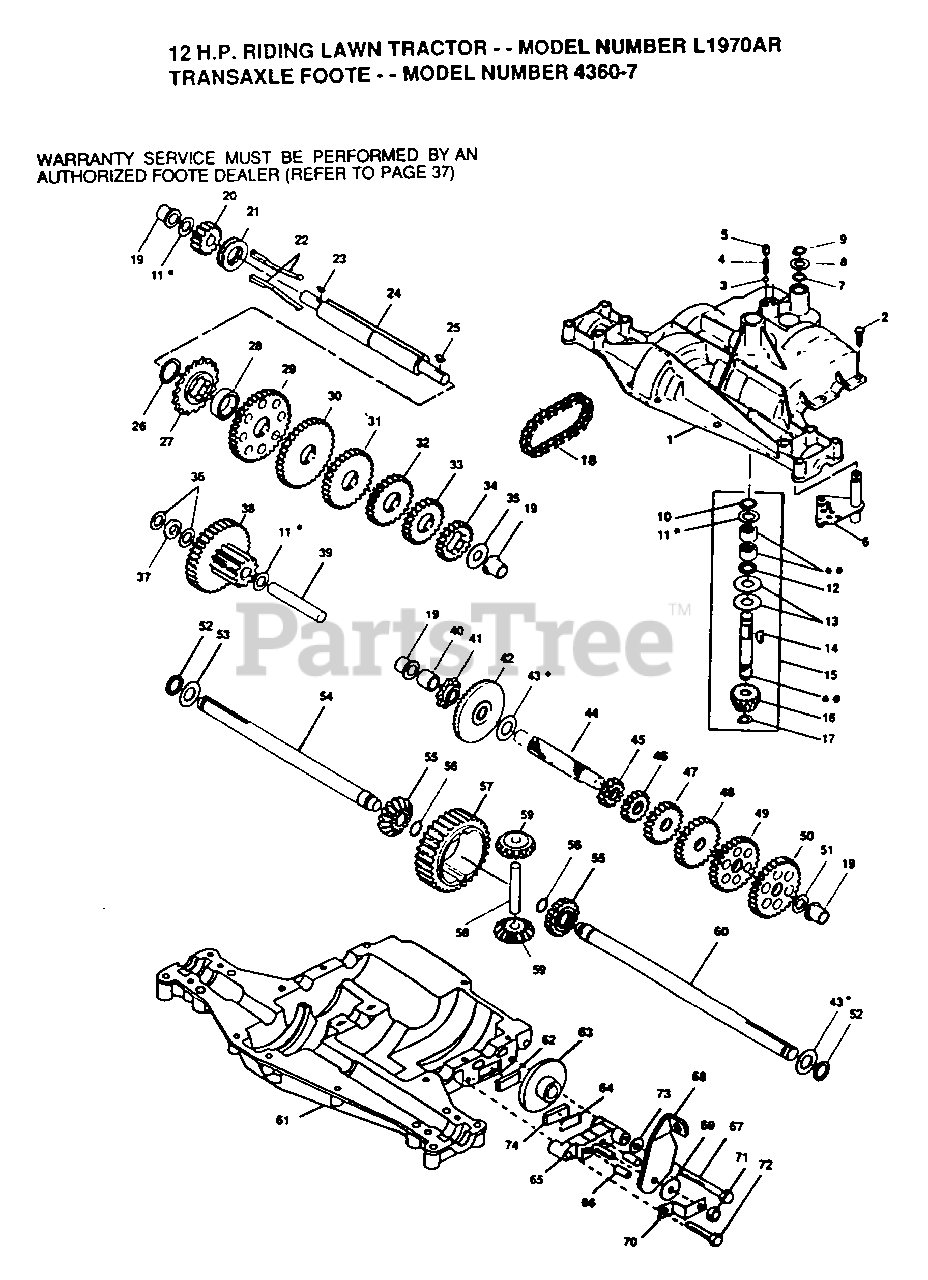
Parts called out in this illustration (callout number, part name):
1	HOUSING UPPER
3	BALL DETENT
4	SPRING, DETENT
5	SCREW, SET
6	ASSY SHIFTER
8	WASHER PLAIN
9	RING RETAINING
10	RING RETAINING
11	WASHER PLAIN
11	WASHER, PLAIN .632 X 1.00 X .026
11	WASHER, PLAIN .632 X 1.00 X .060
13	WASHER, PLAIN .632 X 1.38 X .046
14	KEY WOODRUFF #9
15	ASSY KIT INPUT SHAFT
16	PINION, BEVEL, 14 TEETH
17	RING, RETAINING
18	CHAIN, 24 PITCHES
19	BEARING, FLANGE
20	GEAR SPUR, 14 TEETH
21	COLLAR CLUTCH
22	KEY CLUTCH
23	KEY WOODRUFF #3
24	SHAFT INTERMEDIATE
25	KEY, WOODRUFF, #61
26	RING, RETAINING
27	SPROCKET, 18 TEETH
29	GEAR, SPUR, 37 TEETH
30	GEAR, SPUR, 35 TEETH
31	GEAR, SPUR, 30 TEETH
32	GEAR, SPUR, 25 TEETH
33	GEAR, SPUR, 22 TEETH
35	WASHER, PLAIN .640 X 1.37 X .061
36	WASHER, PLAIN .632 X 1.00 X .026
37	SPACER .630 X 1.00 X .169
38	ASSY GEAR COMB 12&35 TEETH
39	SHAFT IDLER
40	SPACER .635 X .875 X .755
41	SPROCKET, 9 TEETH
42	GEAR, BEVEL, 42 TEETH
43	WASHER PLAIN
43	WASHER, PLAIN .758 X 1.25 X .031
44	SHAFT, DRIVE
45	GEAR, SPUR, 12 TEETH
46	GEAR SPUR, 15 TEETH
47	GEAR, SPUR, 20 TEETH
48	GEAR, SPUR, 25 TEETH
49	GEAR, SPUR, 28 TEETH
50	GEAR, SPUR, 31 TEETH
51	WASHER, PLAIN .632 X 1.00 X .060
53	WASHER PLAIN
54	AXLE LEFT HAND
55	GEAR, MITER, 15 TEETH
56	RING, RETAINING
57	GEAR, SPUR, 32 TEETH
58	SHAFT, CROSS
59	GEAR, MITER, 15 TEETH
60	AXLE, R.H.
61	HOUSING LOWER
62	PUCK, FRICTION
63	DISC, BRAKE
65	JAW, BRAKE
66	PIN, DOWEL
67	SCREW TAPPING
68	LEVER, ACTUATING
69	WASHER, PLAIN .321 X 1.00 X .055
70	BRACKET, ANTI-ROTATION
71	LOCKNUT 5/16-24
72	SCREW TAPPING
73	WASHER PLAIN
74	PUCK, FRICTION
